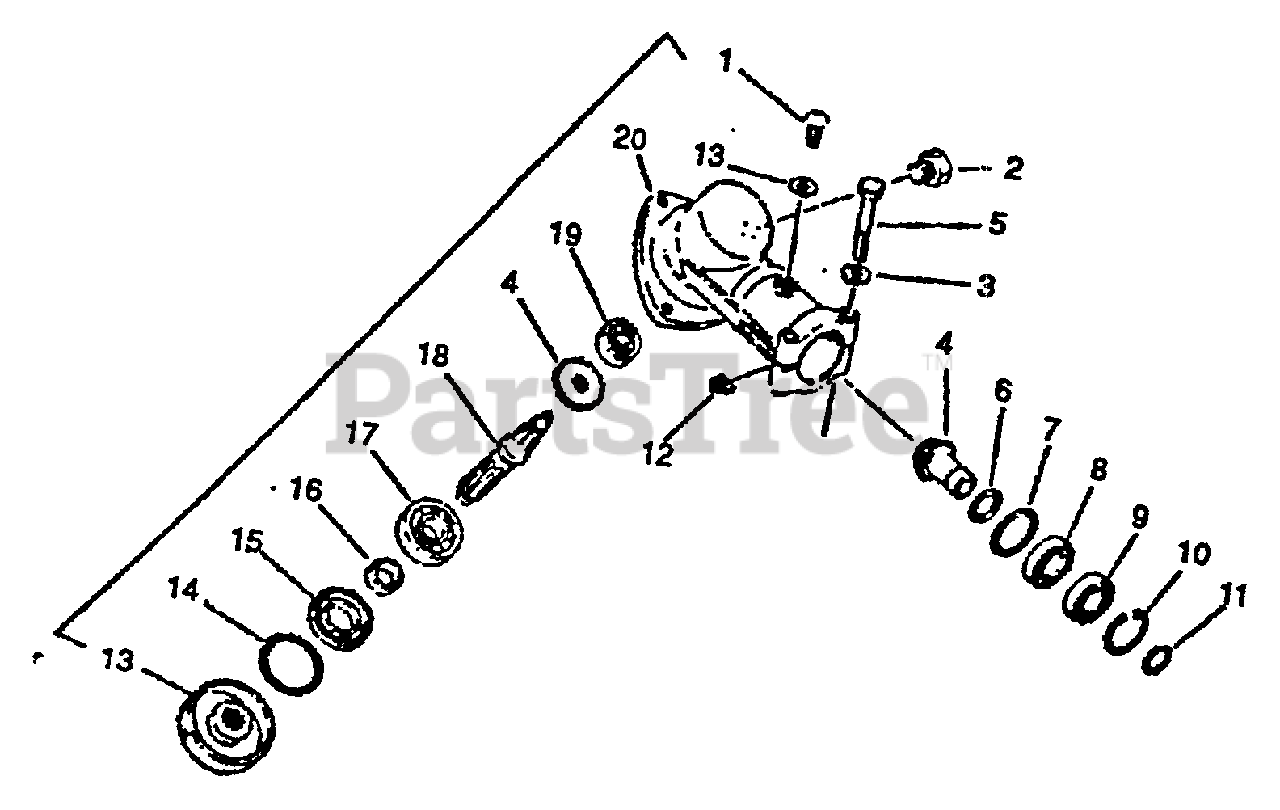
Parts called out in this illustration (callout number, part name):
1	Screw 5X10
3	Washer 5
4	Gear Set
5	Bolt 5X35
6	Washer, Adjustment
7	Washer, Adjustment
8	Bearing, Ball 6900
9	Bearing, Ball 6900
10	Circlip 22
11	Circlip 10
12	Washer, Shim
13	Plate, Adapter
14	Circlip 26
17	Bearing, Ball 6900
18	Shaft, P.T.O
19	Bearing, Ball 626
20	Housing, Gear
